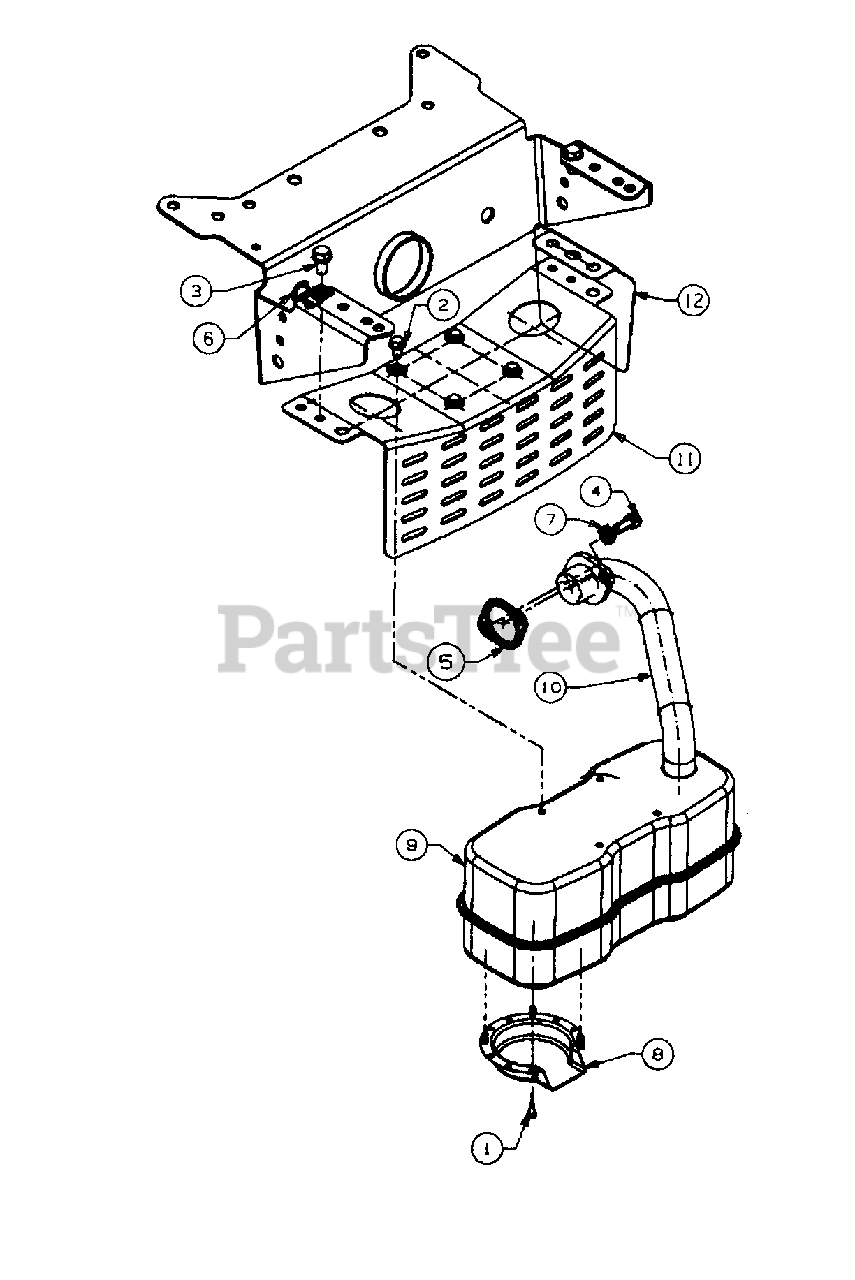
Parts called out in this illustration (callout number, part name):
1	Hex Slot Scr. #8-32 x .38" Lg.
2	Hex Wash. TT-Tap Scr. 1/4-20 x .5" Lg.
3	Hex Wash Hd. TT-Tap Scr. 5/16-18 x .62" Lg.
4	Socket Hd. Bolt 5/16-18 x .62" Lg.
5	Exhaust Gasket
6	Clamp
7	L-Wash. 5/16" I.D.
8	Muffler Deflector
9	Muffler
10	Exhaust Pipe
11	Muffler Bracket
12	Shield Bracket
